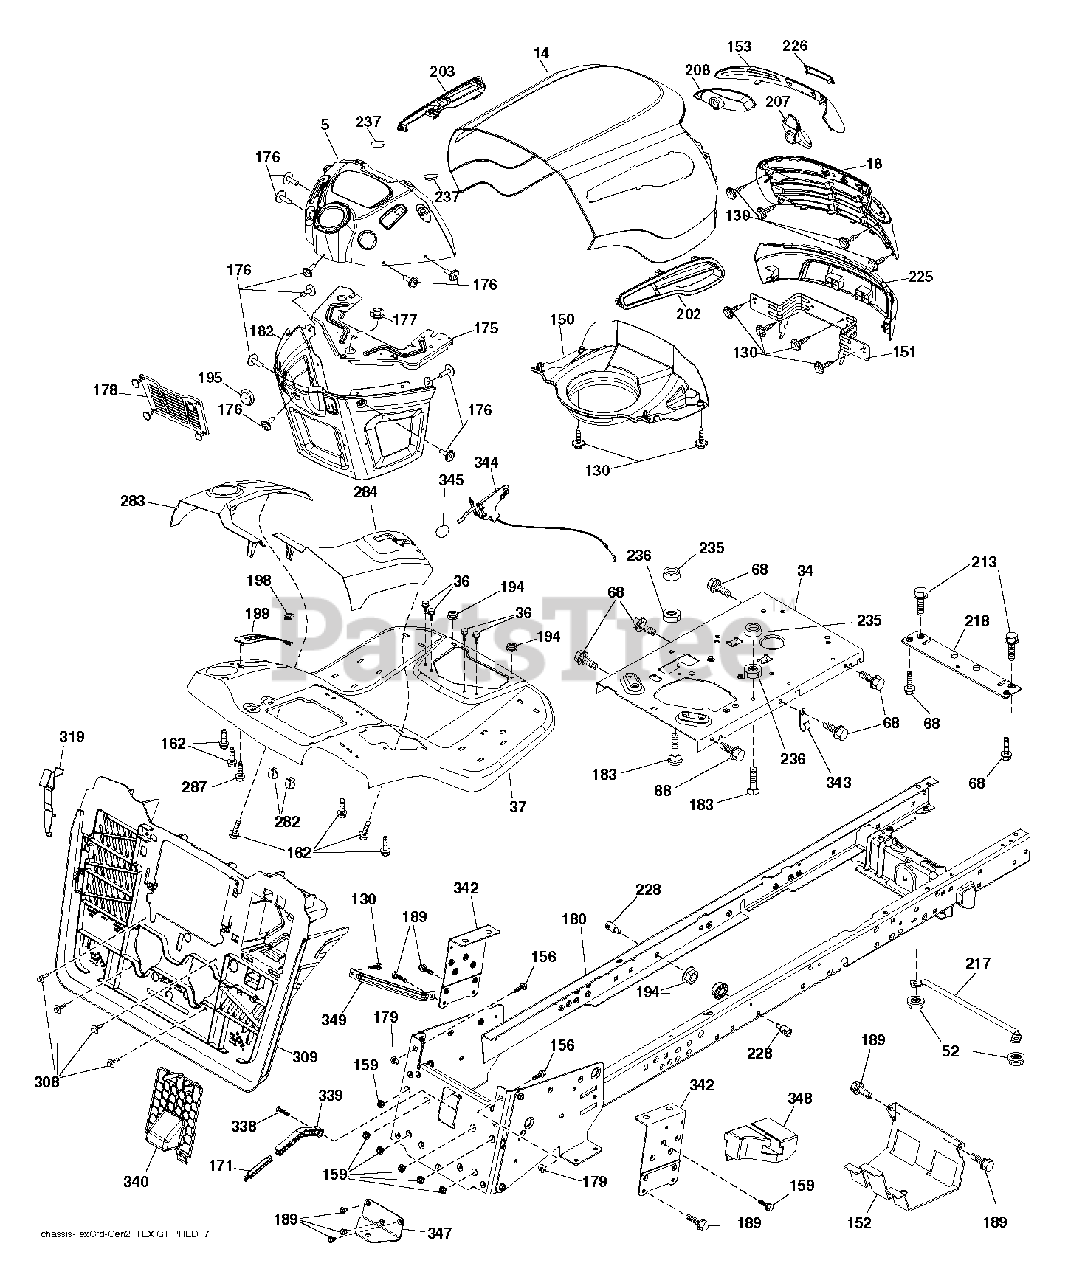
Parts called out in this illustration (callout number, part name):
36	SCREW 5/16"
52	LOCKNUT
130	SCREW.#10 X 0.750.BOS THREAD
152	SHIELD BROWNING
156	BOLT
159	SCREW, 3/8-16X3/4
162	SCREW.HI-LO.CONSOLE
175	PLATE.CROSSMEMBER.HUSQ
176	SCREW.#10-24X5/8.RN.QU
177	BUSHING,STEERING
178	CARGO.ASM.NET.TXGT.W/C
183	BOLT.5/16-18X1-1/4 FULL THD
189	SCREW
194	NUT LOCK HEX FLANGE 5/16-18
195	PLUG.HOLE.DASH.LOWER.12V.BLK
198	INDICATOR.DECK.LIFT.RED
213	BOLT
217	ROD.PIVOT.HOOD
218	X-PIECE.HOOD.STOP.NON/
228	STUD.FASTNER.W/ANTI-ROTATE
235	SPACER FENDER
236	NUT.CENTERLOCK.5/16-
237	PLUG.MOUNT.CARGO.BLK
282	CLIP.RETAINER.CONSOLE.LT.HUSQ
308	BOLT, 5/16-18 X 1 3/4
